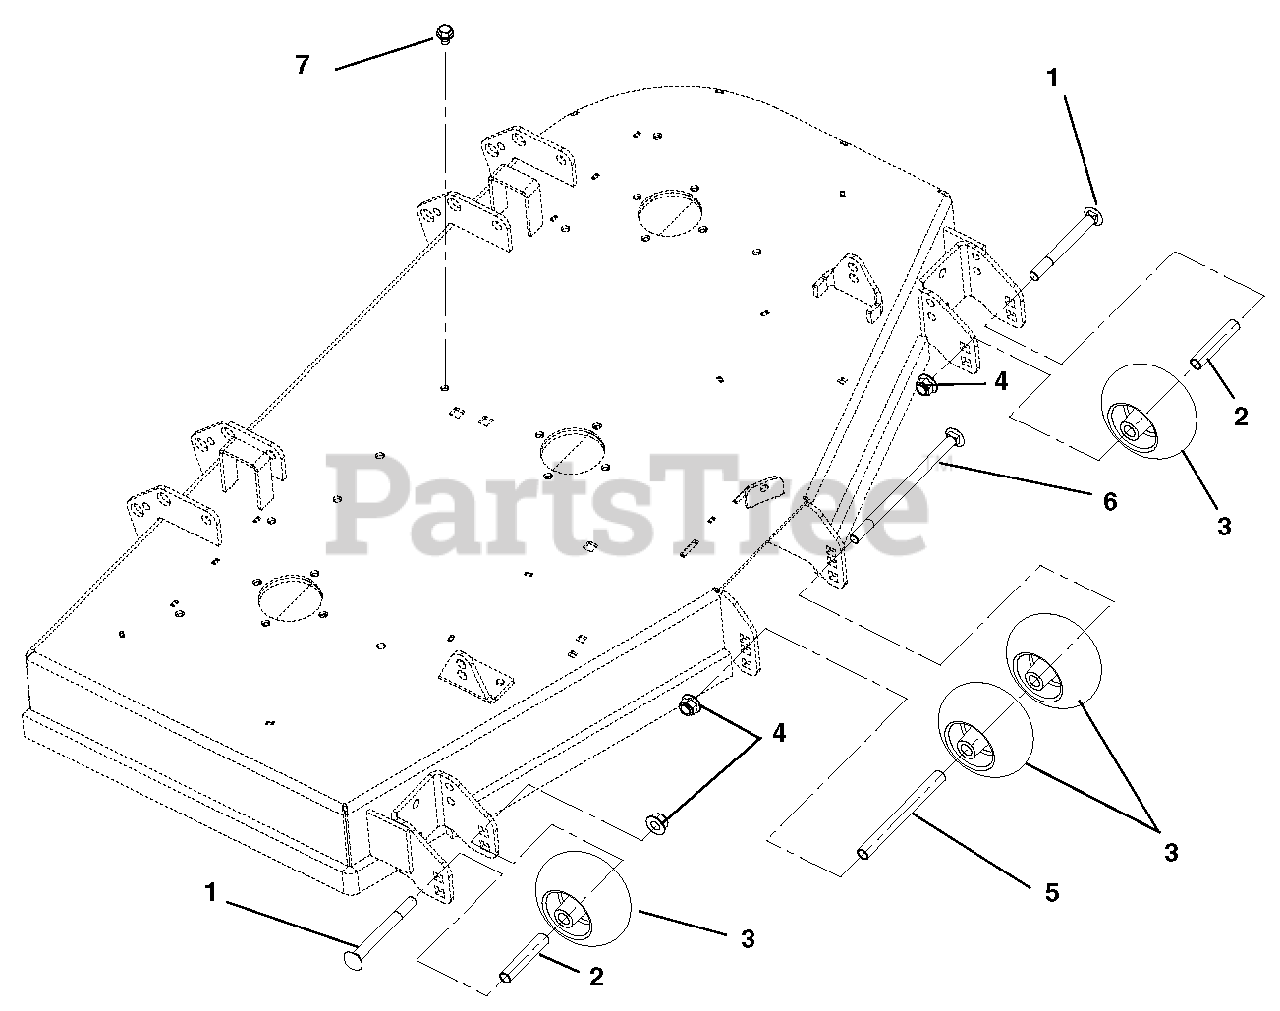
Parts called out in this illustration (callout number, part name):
1	Bolt, Round Head Square Neck .50-13 x 5.00
2	Spacer, .510 x .625 x 3.35
3	Anti-Scalp Wheel
4	Nut, .50-13 Nyloc Flange
6	Bolt, Round Head Square Neck .50-13 x 8.50
7	Screw, Tapping .38-16 x .50 Hex Washer Head
